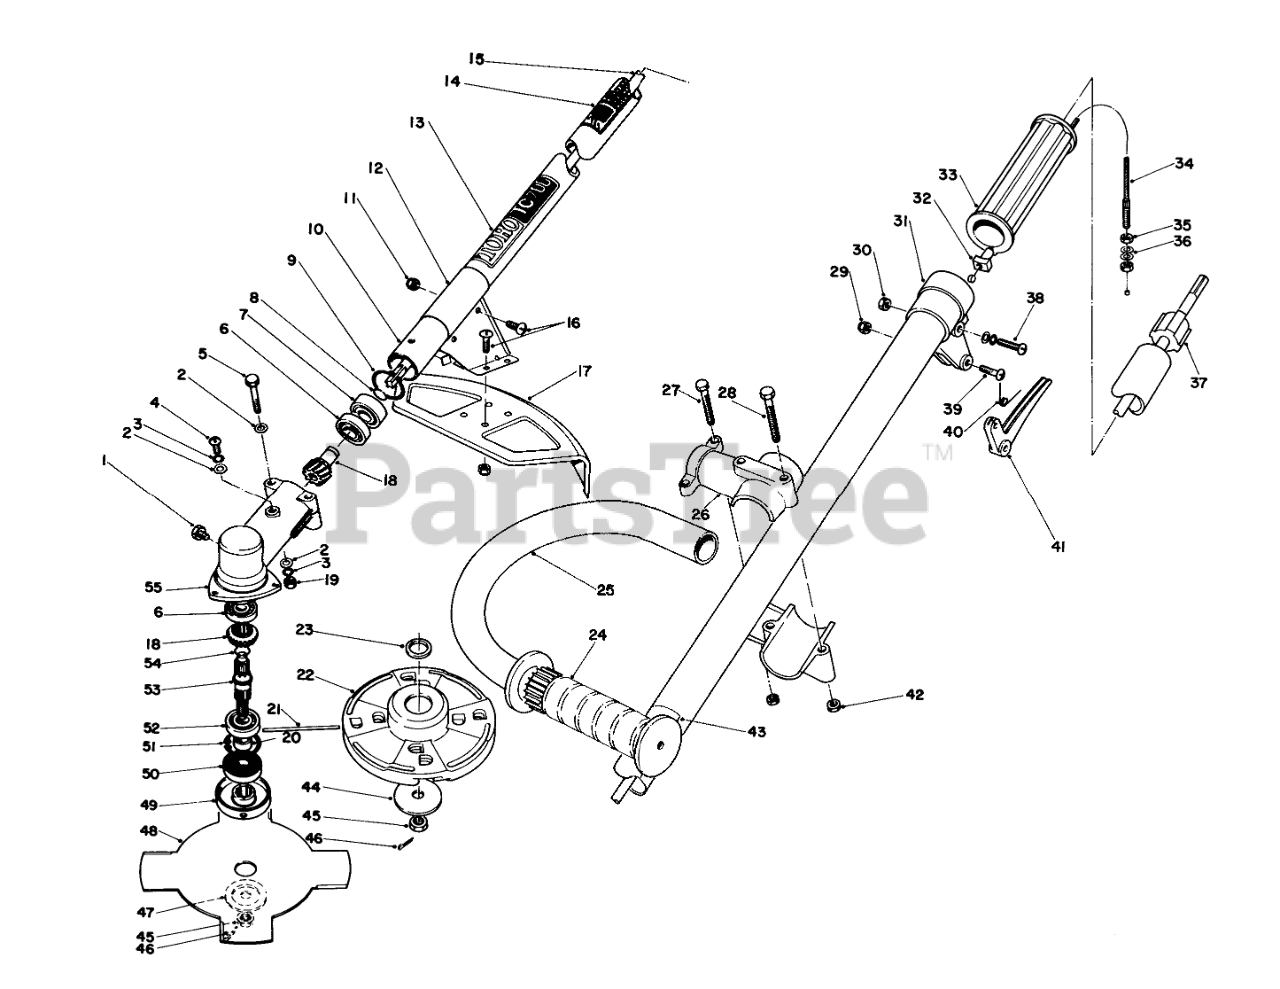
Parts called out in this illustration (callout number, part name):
2	WASHER
3	Washer
4	Screw
6	Ball Bearing
7	Ball Bearing
8	Circlip
9	Circlip
10	Housing Assembly
11	NUT-LOCK, NI
12	Bracket Shield
13	Decal-TC700
14	Decal
15	Shaft Drive
16	SCREW-PPH
17	Shield
18	Gear Set
19	Nut
20	Spacer
21	Filament Line Pkg. (24 Pcs.)
22	Cutter Head (Incl. #23)
23	SPACER
24	LH GRIP
25	Tube-Handle
26	Clamp-"J" Handle
27	10-24X1-1/8 RND HD MS
28	10-24X1-3/4 RND HD MS
30	Nut
31	Bracket, Trigger
32	SPACER
34	Throttle Cable
36	Washer
37	Bushing
38	SCREW
39	Screw
40	Spring Return
41	Throttle Trigger
42	NUT-LOCK, NI
43	Decal Warning
44	WASHER
46	Split Pin
47	Blade Adapter Kit (Incl. Ref. #45 & 46)
48	Brush Blade
49	Plate-Blade Fixing
50	Oil Seal
51	Circlip
52	Ball Bearing
53	Shaft P.T.O.
54	Circlip
55	Gear Housing
